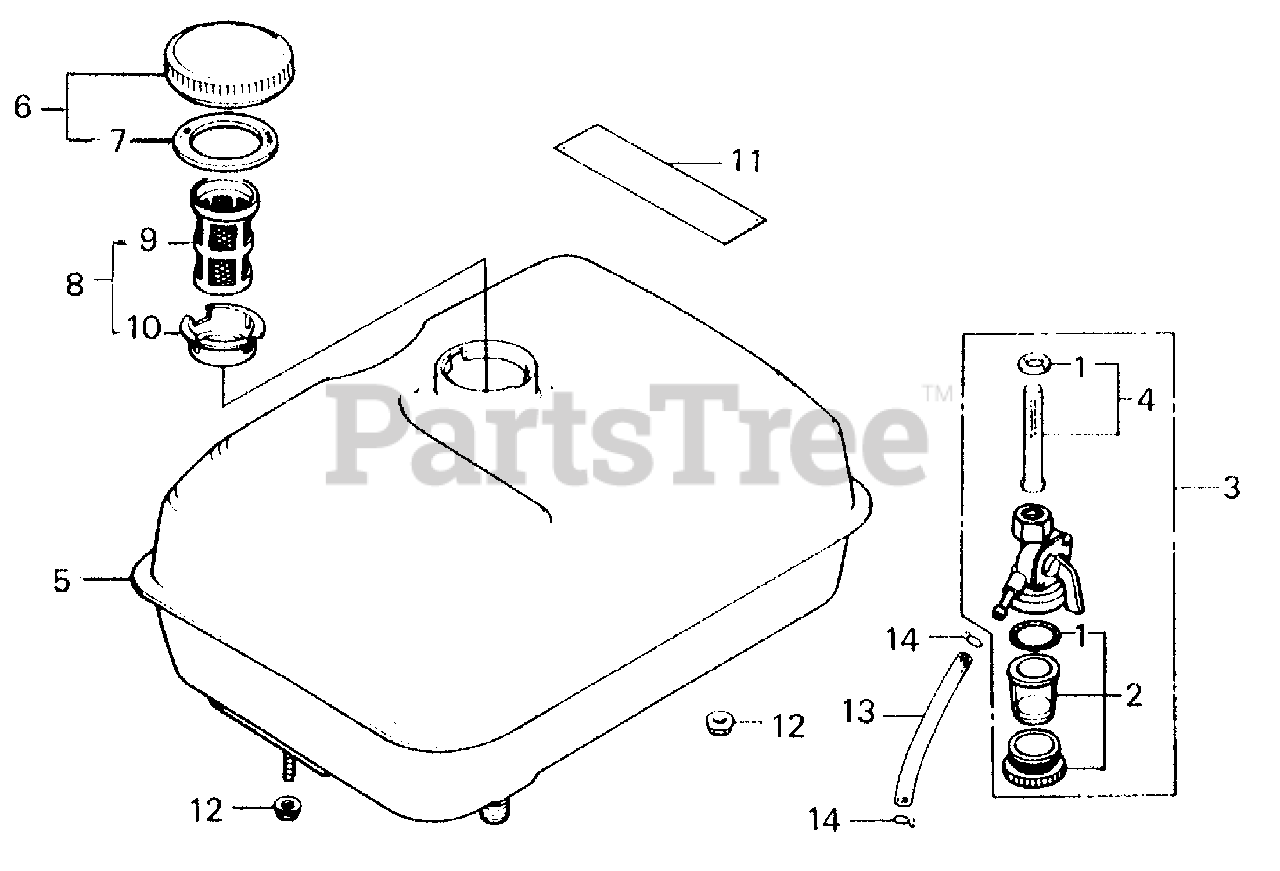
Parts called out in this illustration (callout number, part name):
1	GASKET SET, VALVE
2	CUP SET, FUEL STRAINER
3	PETCOCK ASSY.
4	SCREEN SET
5	TANK, FUEL *NH31* (MCKINLEY WHITE)
6	CAP, FUEL FILLER
7	GASKET, FUEL FILLER CAP
8	FILTER, FUEL
9	FILTER, FUEL
10	HOLDER, FUEL FILTER
11	MARK, CAUTION (ENGLISH/FRENCH)(SPANISH)
12	NUT, FLANGE (6MM)
13	BULK HOSE, FUEL (4.5X3000) (4.5X65)
13	BULK HOSE, FUEL (4.5X3000) (4.5X70)
14	CLIP, TUBE (B8)
